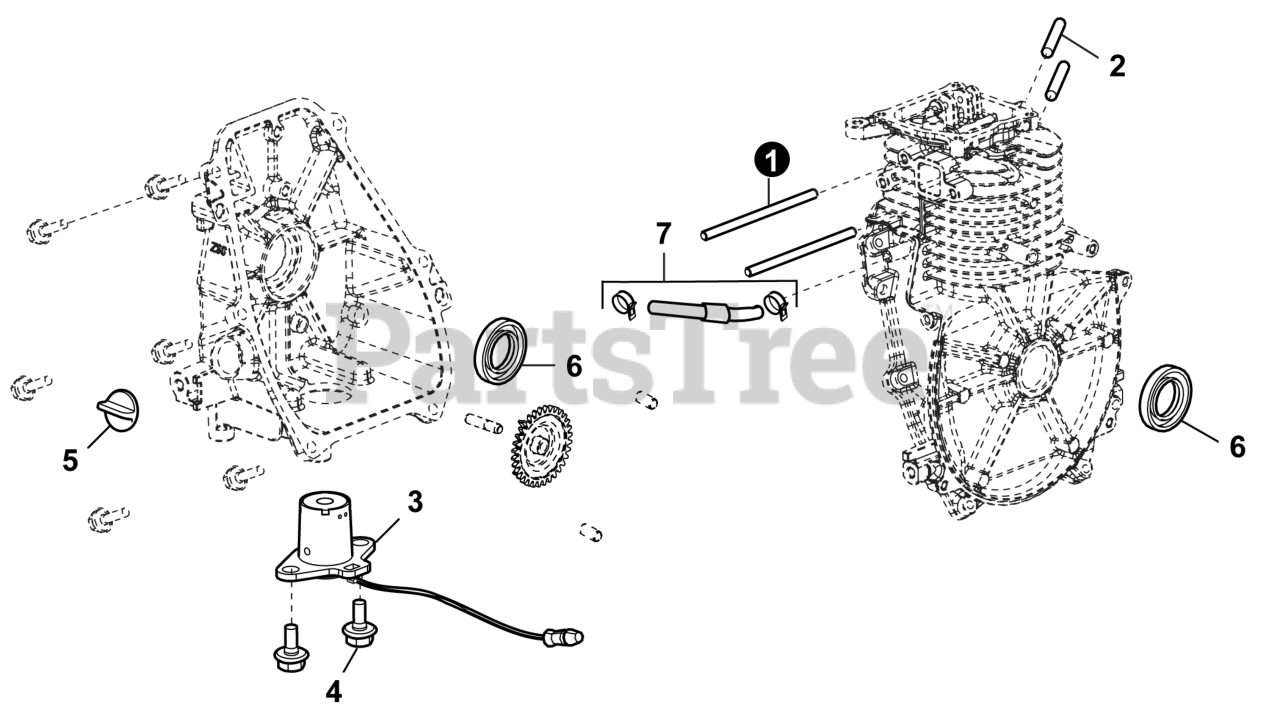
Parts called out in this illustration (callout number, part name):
1	STUD, EXHAUST
2	STUD, INTAKE
3	SENSOR, ENGINE OIL
5	PLUG, ENGINE OIL
6	SEAL, OIL
7	PIPE ASSY.
